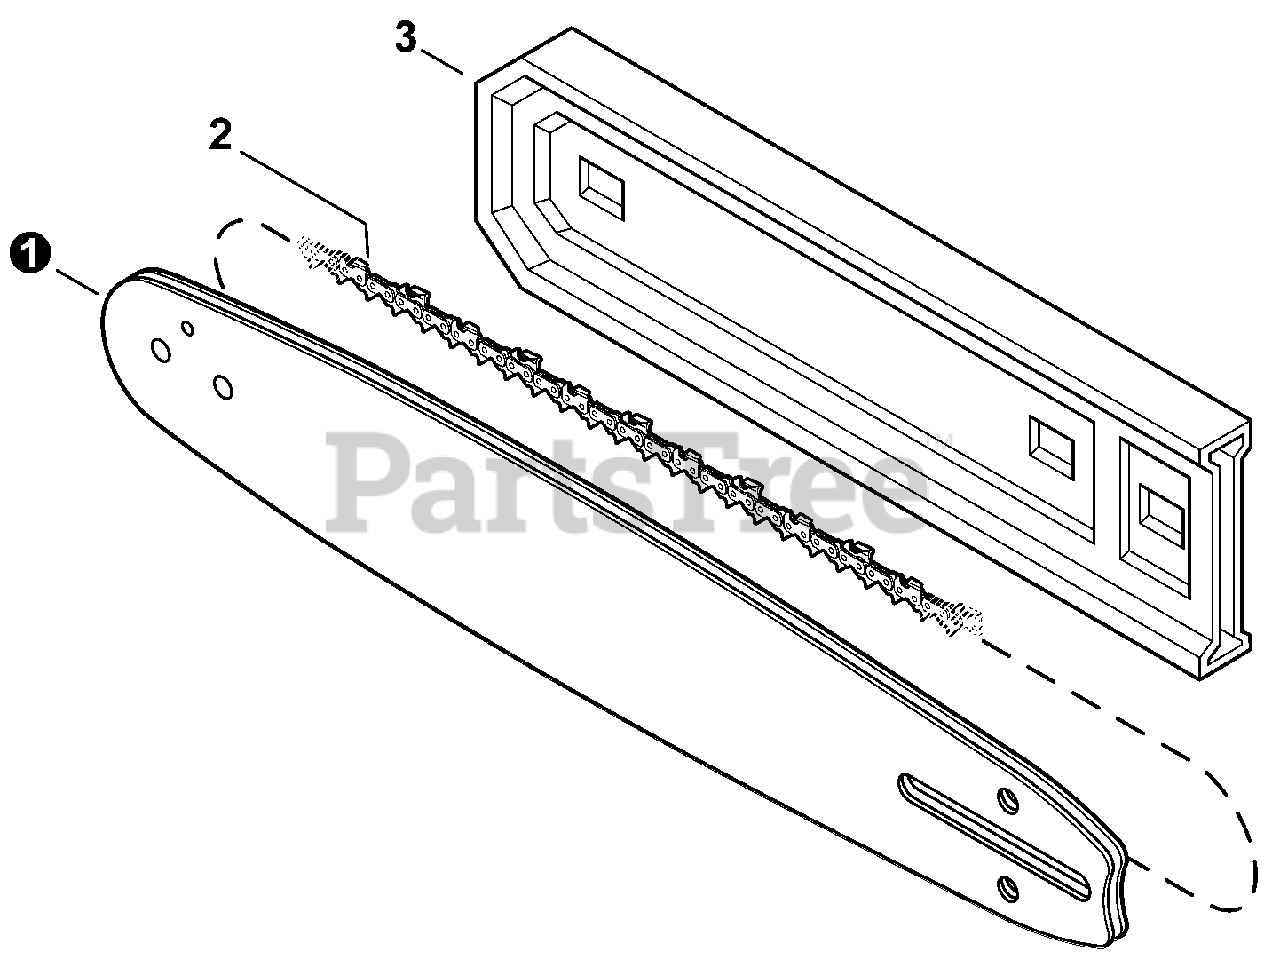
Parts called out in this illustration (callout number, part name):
1	GUIDE BAR, 10" 0.050" GA
2	SAW CHAIN 10" 0.050" GA
3	SCABBARD 10"
